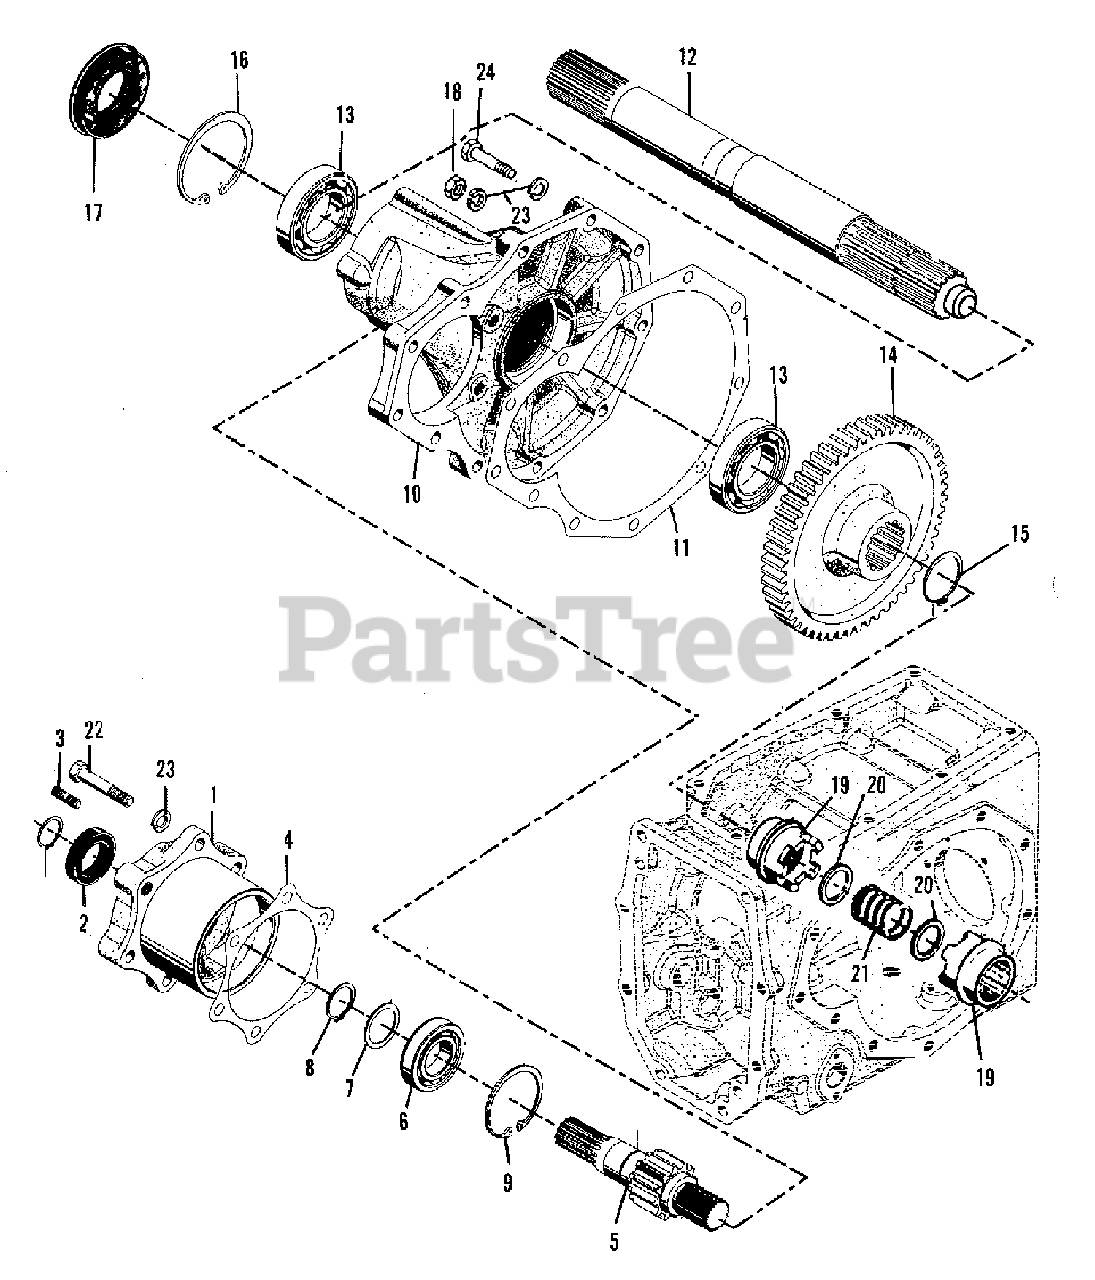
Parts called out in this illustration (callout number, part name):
1	HOUSING ASSEMBLY, R.H., axle pinion (Incl. Items 2 & 3)
2	SEAL, oil
3	STUD, M10 x 18
4	SHIM (0.1)
4	SHIM (0.15)
4	SHIM (0.2)
4	SHIM (0.3)
4	SHIM (0.5)
5	SHAFT, R.H., axle pinion
6	BEARING, ball (One side sealed)
7	WASHER, thrust
8	RING, M35, snap - external
9	RING, M72, snap - internal
12	AXLE, final drive
13	BEARING, ball
14	GEAR, final drive
15	RING, M50, snap-external
16	RING, M90, snap-internal
17	SEAL ASSEMBLY, oil
19	COUPLING, differential lock
20	WASHER, thrust
21	SPRING, differential lock
22	SCREW, M12 x 65
23	LOCKWASHER, M12
24	CAPSCREW, M12 x 45
